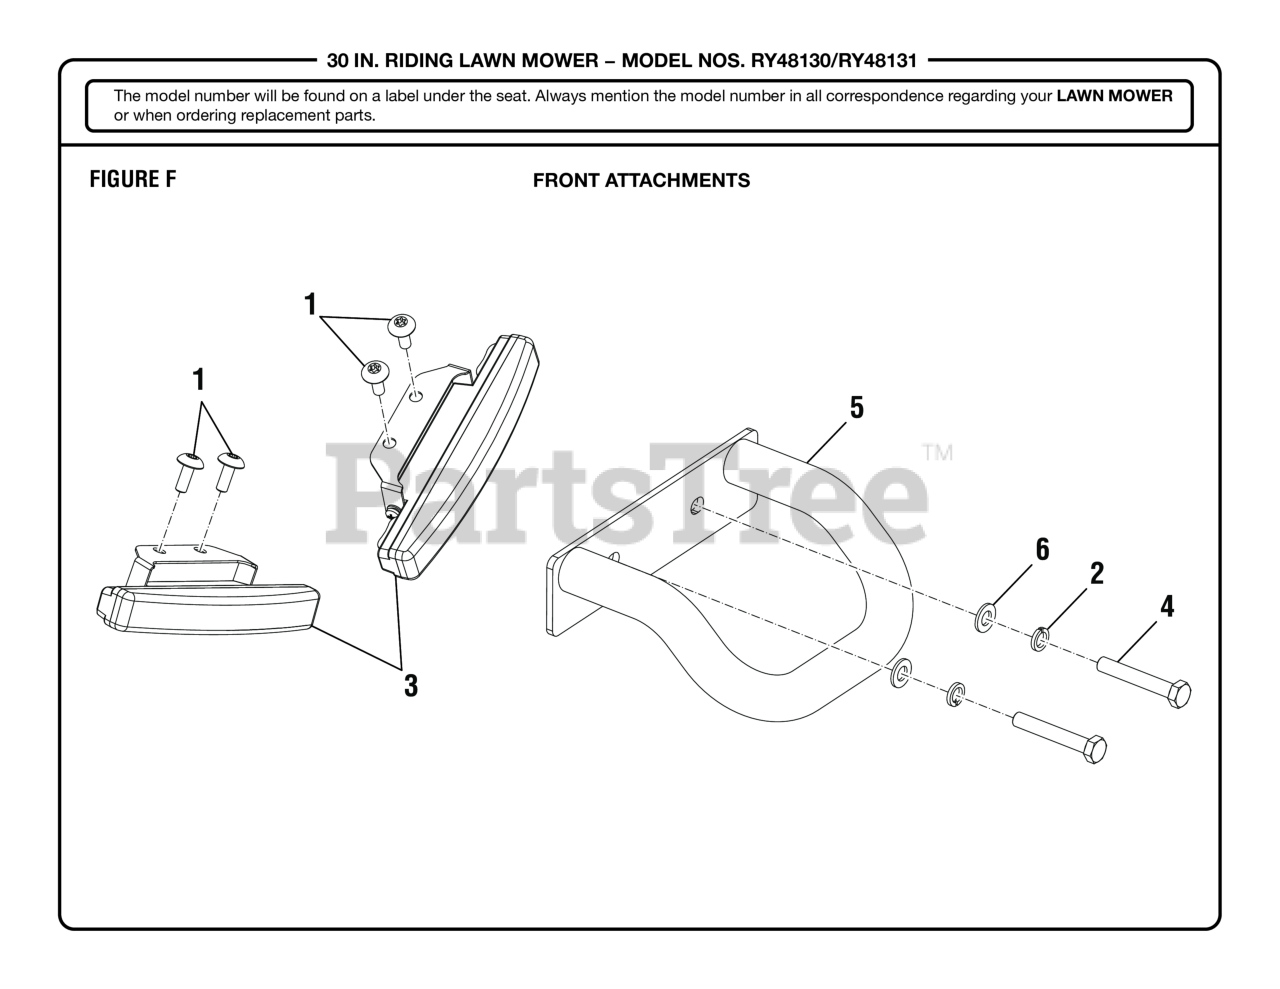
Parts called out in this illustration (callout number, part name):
1	Screw (M6 x 10 mm, Soc. Button Hd.)
2	Lock Washer (OD9.8 x ID8.5 x 5t)
3	Light Assembly
4	Bolt (M8 x 50 mm, Hex Hd.)
5	Front Bumper
6	Washer (OD16 x ID8.4 x 1.6t)
